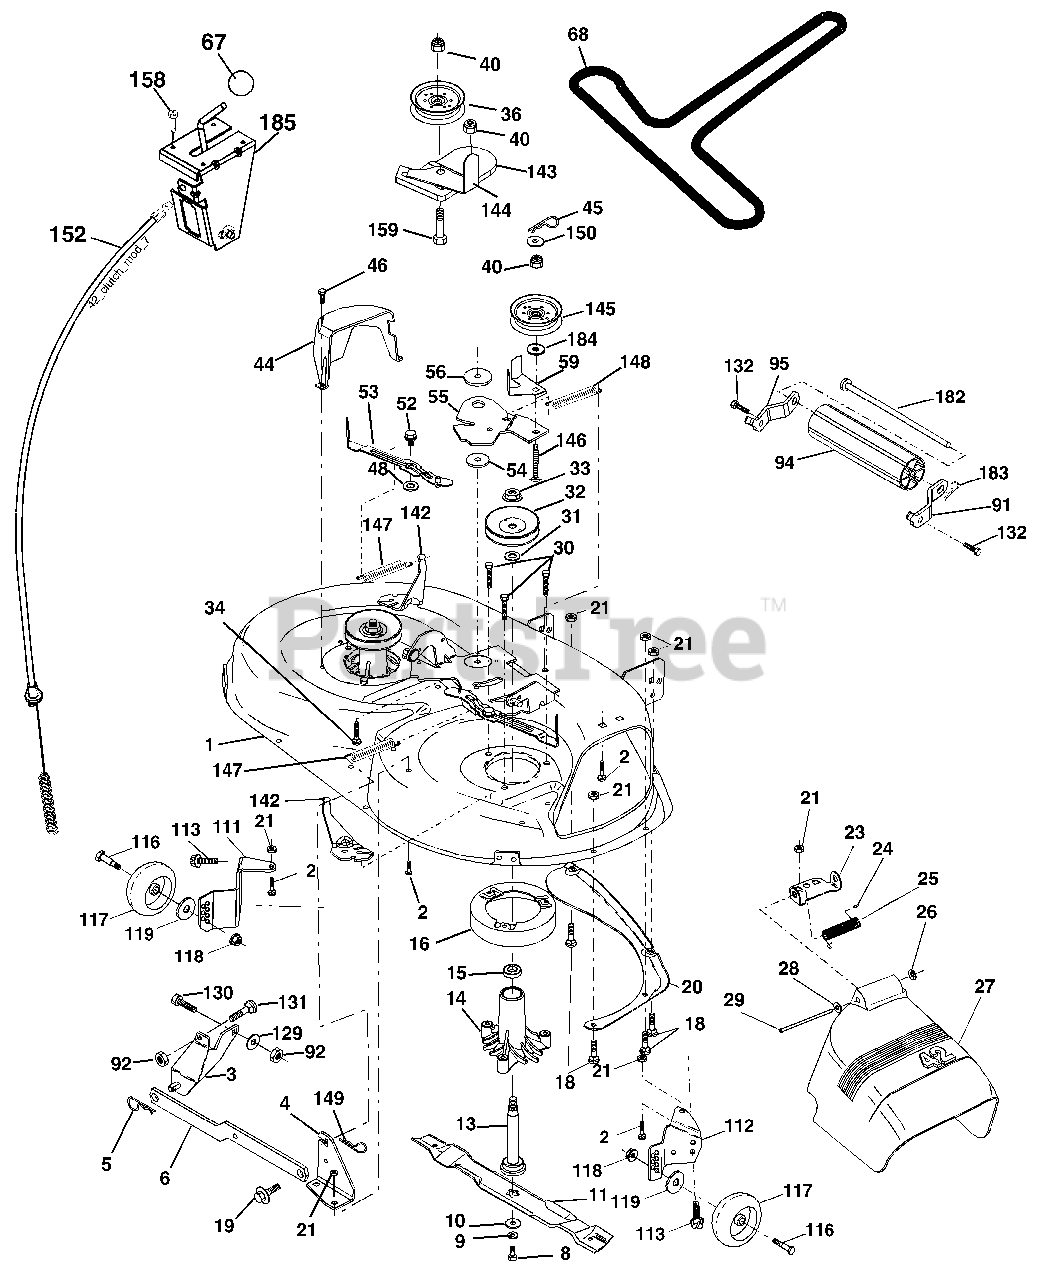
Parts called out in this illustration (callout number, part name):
1	Deck Asm MWR 42"weldment
2	Bolt Rdhd Sqnk 5/16-18unc X3/4
3	Bracket Asm Fr Sway Bar 38/42
4	Bracket Asm Deck 42"sway Bar
5	Retainer Spring
6	Deck Sway Bar
8	Bolt 3/8 - 24 X 1.25 Gr 8
9	Washer Lock Hvy 3/8
10	Washer Hard Blade Mower Vented
11	Blade, 42" Mulching Std
11	Blade, 42" Mulching Premium
11	Blade, 42" Hi-Lift
13	Shaft Asm W/lower Bearing
14	Housing Mandrel Vented
15	Bearing Ball Mandrel
16	Stripper Mower
18	Bolt Rdhd Sqnk 5/16-18 X 5/8
19	Bolt Shoulder
20	Baffle Vortex 42
21	Nut Crownlock 5/16-18 UNC
23	Bracket Deflector Mower 42"
24	Cap Sleeve 80x 112 Blk Mower
25	Spring Torsion Deflector 2 52
26	Nut Push Phos & Oil
27	Shield Deflector Mower 42" Blk
28	Washer 11/32 X 5/8 X 16 Ga
29	Rod Hinge 42"6 75 Wlg
30	Screw Thd Rolling
31	Washer Spacer
32	Pulley Mandrel 42"
33	Nut Toplock Flng
34	Bolt Carr SH 3/8-16 x 1-1/2 Gr. 5
36	Pulley Idler Flat 3 060
40	Nut Lock FLg 3/8-16 unc
44	Guard Mandrel LH Black
45	Spring Retainer 1" Zinc/cad
46	Screw Hex Thd Cut 1/4-20 x 5/8 T
48	Washer Hardened Smaller
52	Bolt Shoulder 5/16-18 Unc Blkz
53	Arm Asm Pad Brake
54	Washer Hardened
55	Arm Idler 42"mower LT/YT
56	Spacer Retainer Mower
59	Guard TUV Idler
67	Knob Rd 3/8-16 Plstc Thds Blk
68	V-Belt Mower 42"
91	Bracket Roller Nose LH
92	Nut Lock Hex w/Ins. 3/8-16 Unc
94	Roller Nose
95	Bracket Roller Nose RH
111	Bracket Wheel Gauge LH 42" Deck
112	Bracket Gauge Wheel RH 42" Deck
113	Bolt 5/16-18
116	Bolt Shoulder
117	Wheel Gauge
118	Nut Centerlock 3/8-16 UNC
119	Washer 3/8 x 7/8 x 14 Ga.
129	Washer 13/32 x 13/16 x 12 Ga.
130	Bolt Rd Hd Sqnk 3/8-16 Unc x 1
131	Bolt Fin Hex 3/8-16 Unc x 1 Gr. 5
132	Screw Hex Wsh Thdr. 3/8-16 x 3/4
142	Arm Spring Brake Mower
143	Bracket Arm Idler 42"
144	Keeper Belt 42" Clutch
145	Pulley Idler Flat
146	Bolt Carriage Idler
147	Spring Extension
148	Spring Return Idler
149	Retainer Spring Yellow
150	Washer 9/32 x 3/4 x 16 Ga.
152	Clutch Cable 42"
158	Screw Hex Thd Cut 1/4-20 x 1/2
159	Bolt Rdhd Sqn 3/8-16 Unc x 1-3/4
182	Rod Roller Nose
183	Retainer Spring
184	Washer 13/32 x 7/8 x 10 Ga.
185	Head Asm Cable Clutch
